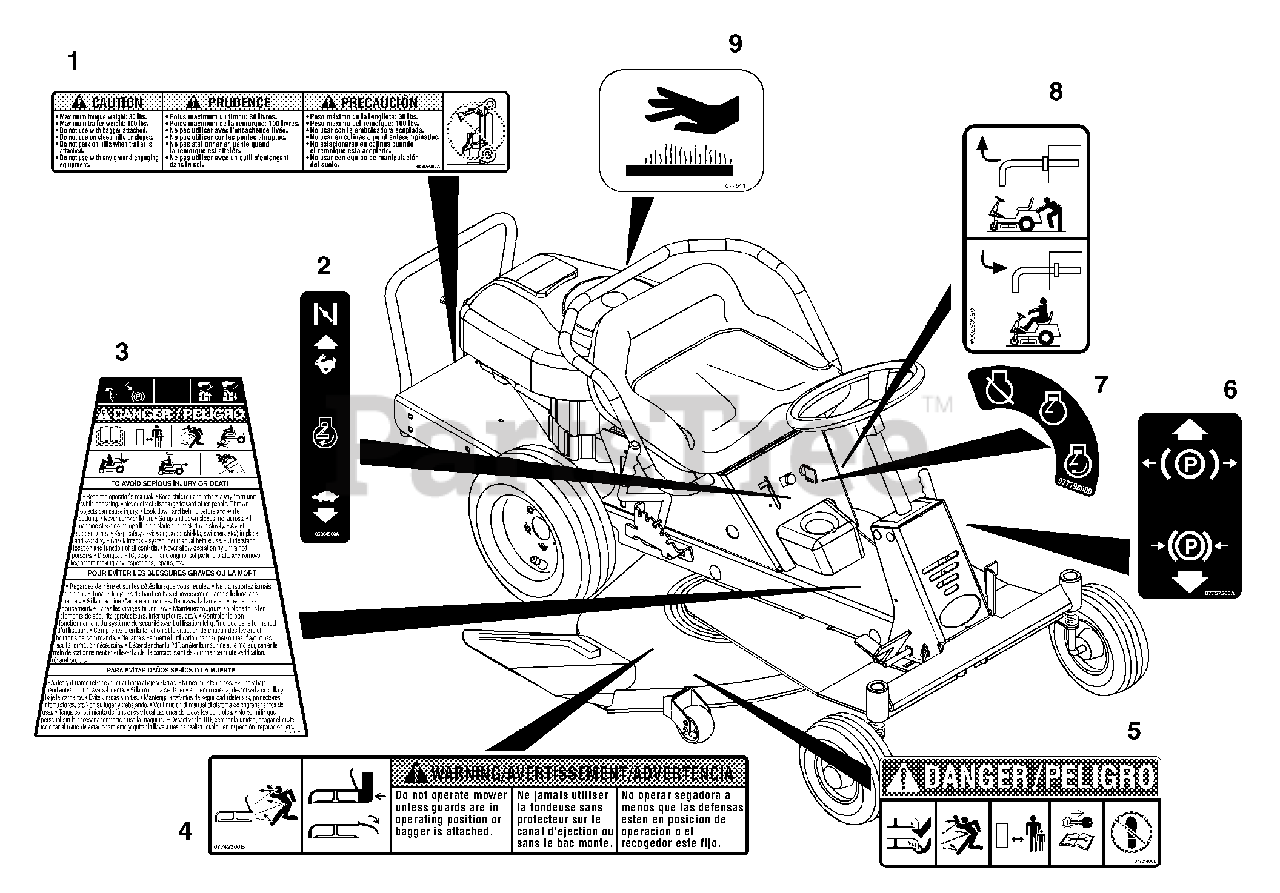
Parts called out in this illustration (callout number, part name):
1	DECAL-HITCH 100#
2	DECAL-THROTTLE RER/SPORT
3	DECAL-RER WARNING
4	DECAL, WARNING
5	DECAL, MOWER PAN DANGER
6	DECAL, PARKING BRAKE LEVER
7	DECAL - IGNITION
8	DECAL, TRANS DISCONNECT
9	DECAL, HOT SURFACE
